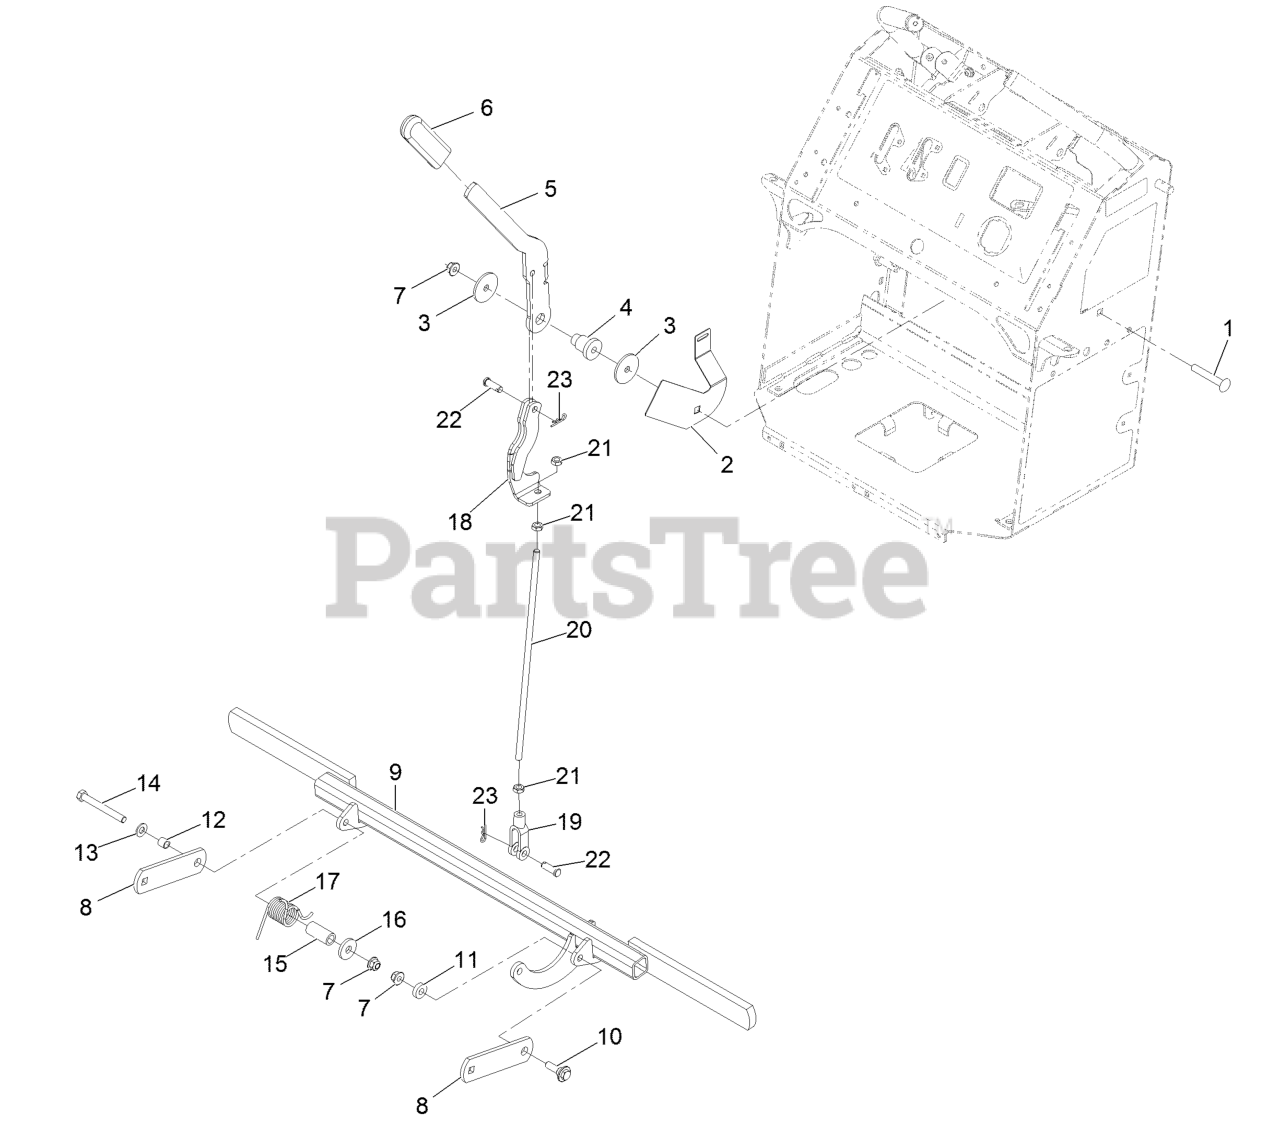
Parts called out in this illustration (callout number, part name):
1	Bolt-Carriage 3/8-16 X 2 1/2
2	Plate-Switch, Brake
3	Washer-Rebound
4	Mount-Pulley
5	Lever-Brake
6	Grip-Lever
7	Nut-Nyloc 3/8-16 Flg
8	Support-Brake
9	Bar-Brake
10	Screw-Shoulder 3/8-16 X 1.295
11	Spacer
13	Washer-3/8 SAE
14	Screw-HH 3/8-16 X 3-1/4
16	Spring-Torsion
18	Arm-Brake
19	Yoke-Linkage, Brake
20	Rod-Brake
21	Nut-Jam 3/8-24
22	Pin-Clevis 3/8 X 1 1/6
23	Pin-Cotter
